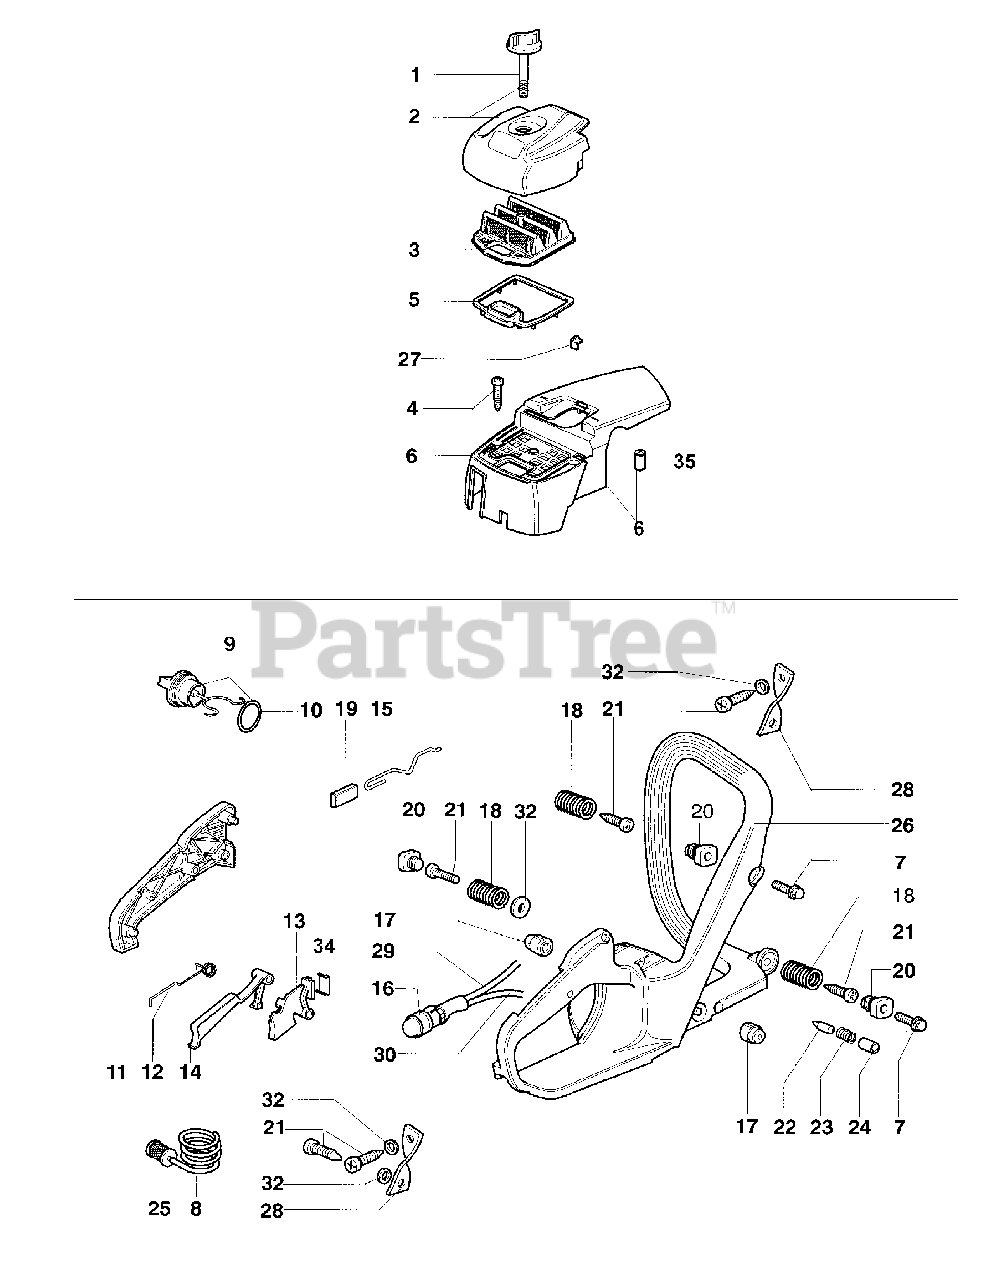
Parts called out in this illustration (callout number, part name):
2	FILTER COVER
12	SPRING
13	THROTTLE LEVER
14	THROT. INTERLOCK
15	THROTTLE ROD
17	SHOCK ABSORBER
19	ROD CAP
22	TANK BREATHER
24	TANK BREATHER
25	fuel filter
26	COMPL. FUEL TANK
